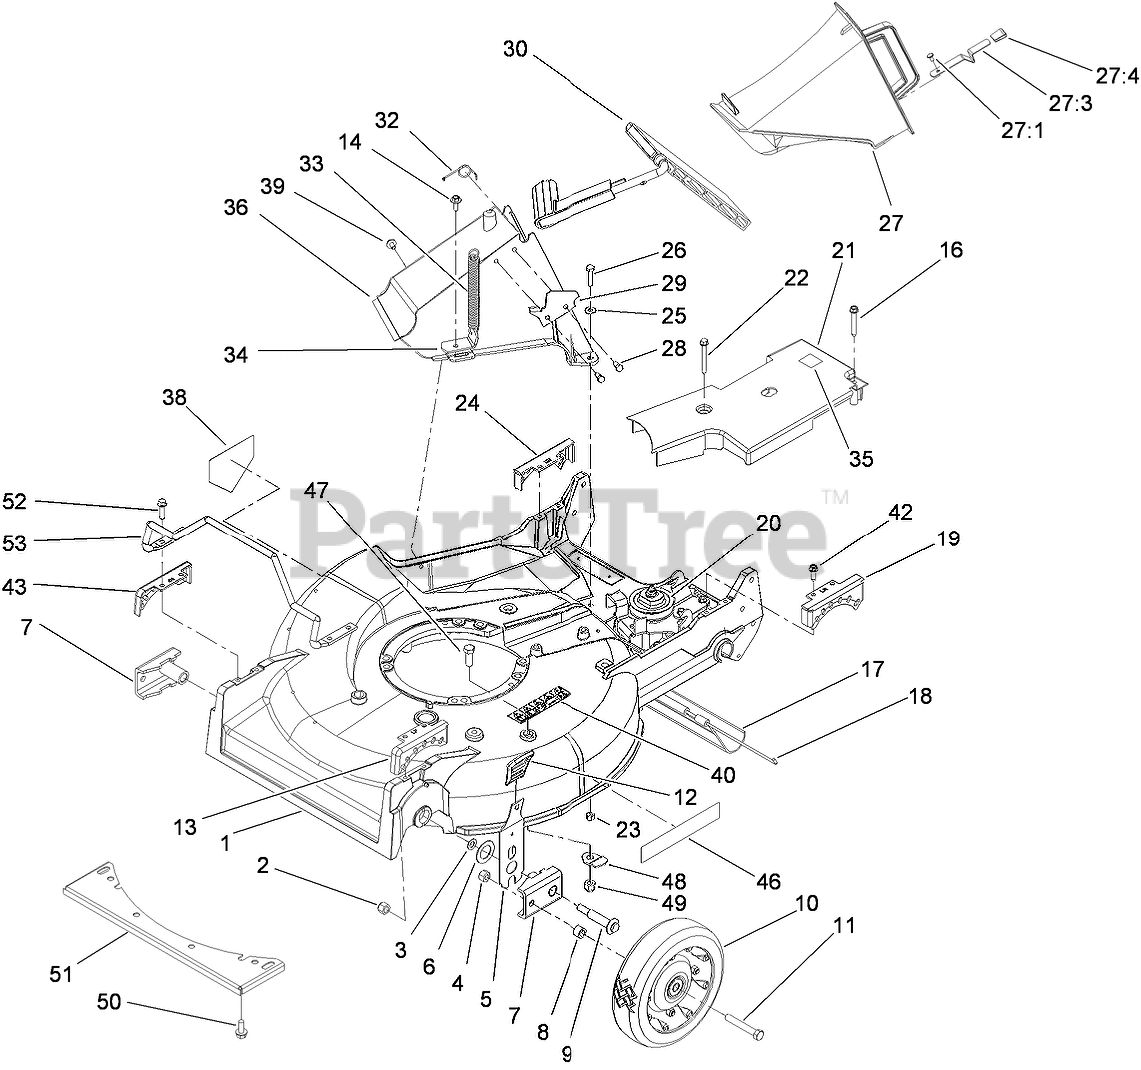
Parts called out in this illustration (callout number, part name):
1	HOUSING
2	NUT-LOCK
3	WASHER
4	NUT-LOCK, CONE
5	FRONT SPRING ARM ASM
6	WASHER-THRUST
7	ARM-PIVOT, FRONT
8	SPACER-WHEEL
9	SCREW-SHOULDER
10	Wheel and Tire ASM
11	SCREW-HH
12	KNOB-HOC
13	QUADRANT-FRONT, LH
14	SCREW-HWH
16	SCREW-HWHTF
17	SHIELD-TRAILING
18	ROD-SHIELD
19	QUADRANT-REAR, LH
20	GEAR CASE ASM
21	COVER-BELT
22	SCREW-HHFTF
23	NUT-LOCK, NI
24	QUADRANT-REAR, RH
25	WASHER-FLAT
26	SCREW-HH
27	DISCHARGE PLUG ASM
27:1	RIVET-HEAD, FLAT
27:3	LATCH-PLUG, DISCHARGE
27:4	GRIP-LATCH
28	SCREW-PLASTITE
29	LATCH-PLATE
30	DISCHARGE DOOR ASM
32	RETAINER-DOOR
33	SPRING-DOOR
34	BRACKET-SPRING
35	DECAL-GREASE
36	TUNNEL-DISCHARGE
38	DECAL-DANGER
39	SCREW AND WASHER ASM
40	DECAL-DANGER
42	SCREW-HWHTF
43	QUADRANT-FRONT, RH
47	SCREW-HH
48	SHIELD-RETAINER
49	NUT-LOCK, NI
50	SCREW-HWHTF
52	SCREW-HWHTF
53	GUARD-ENGINE
